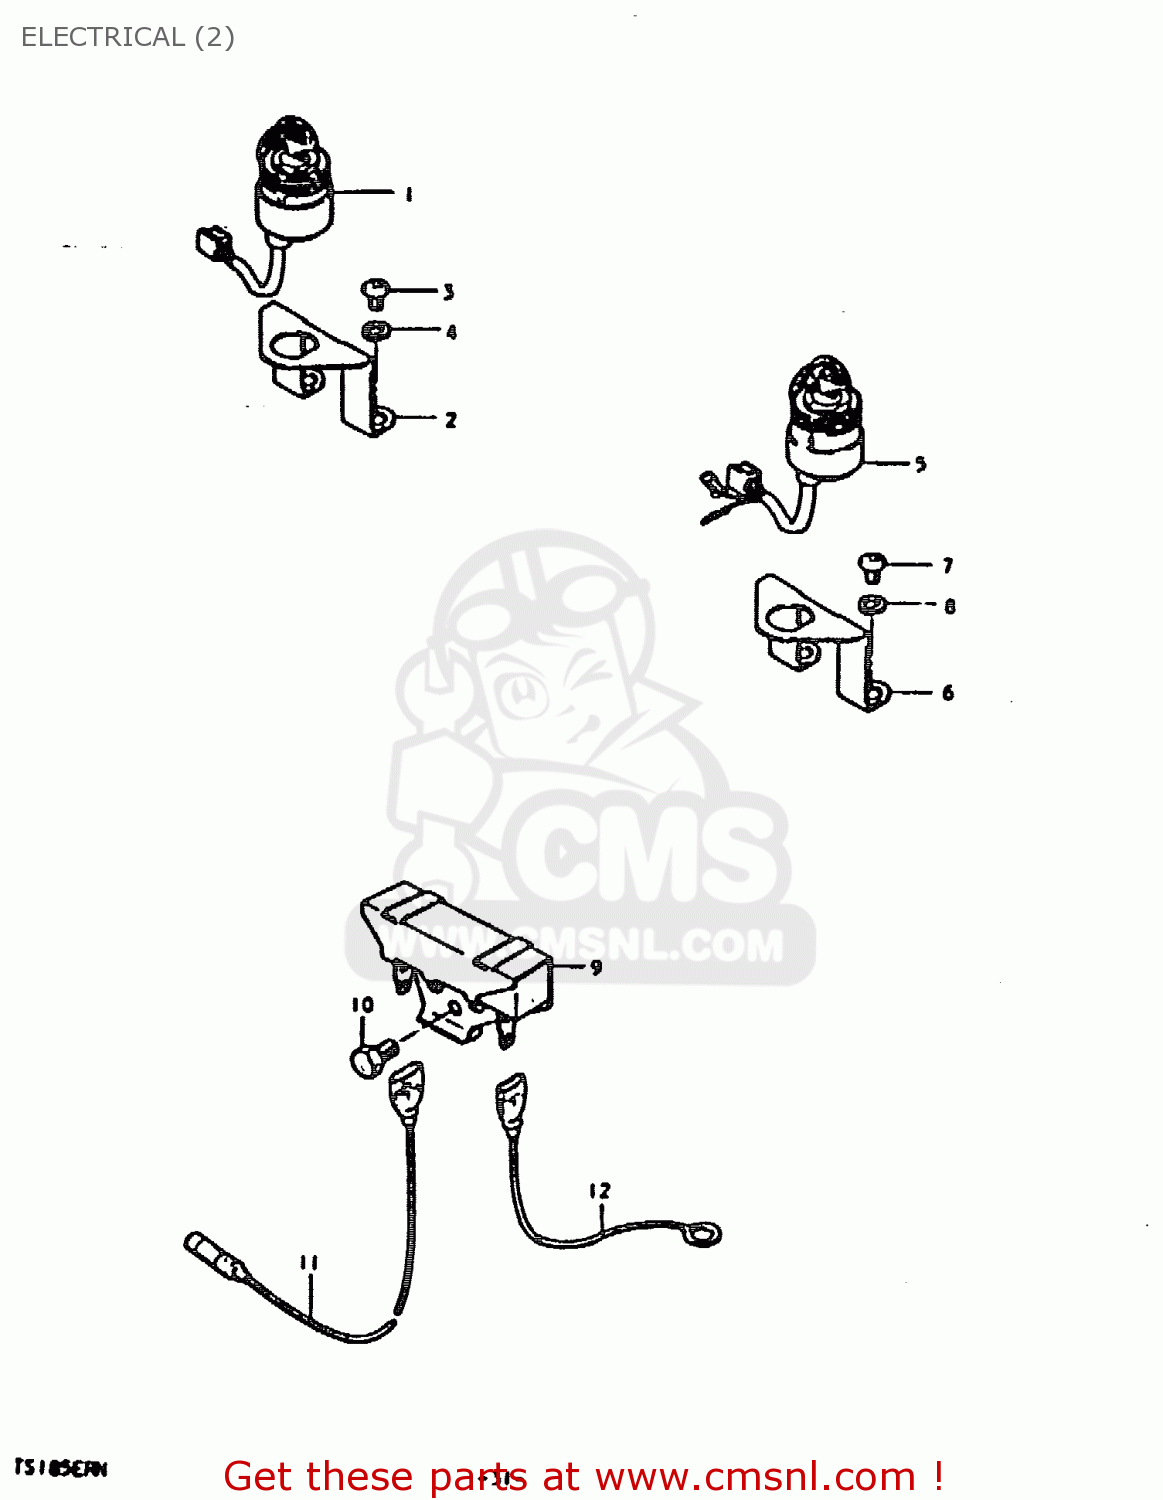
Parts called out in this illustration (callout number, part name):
5	SWITCH ASSY, IGNITION
6	BRACKET, IGNITION SWITCH
7	SCREW
8	LOCK WASHER
